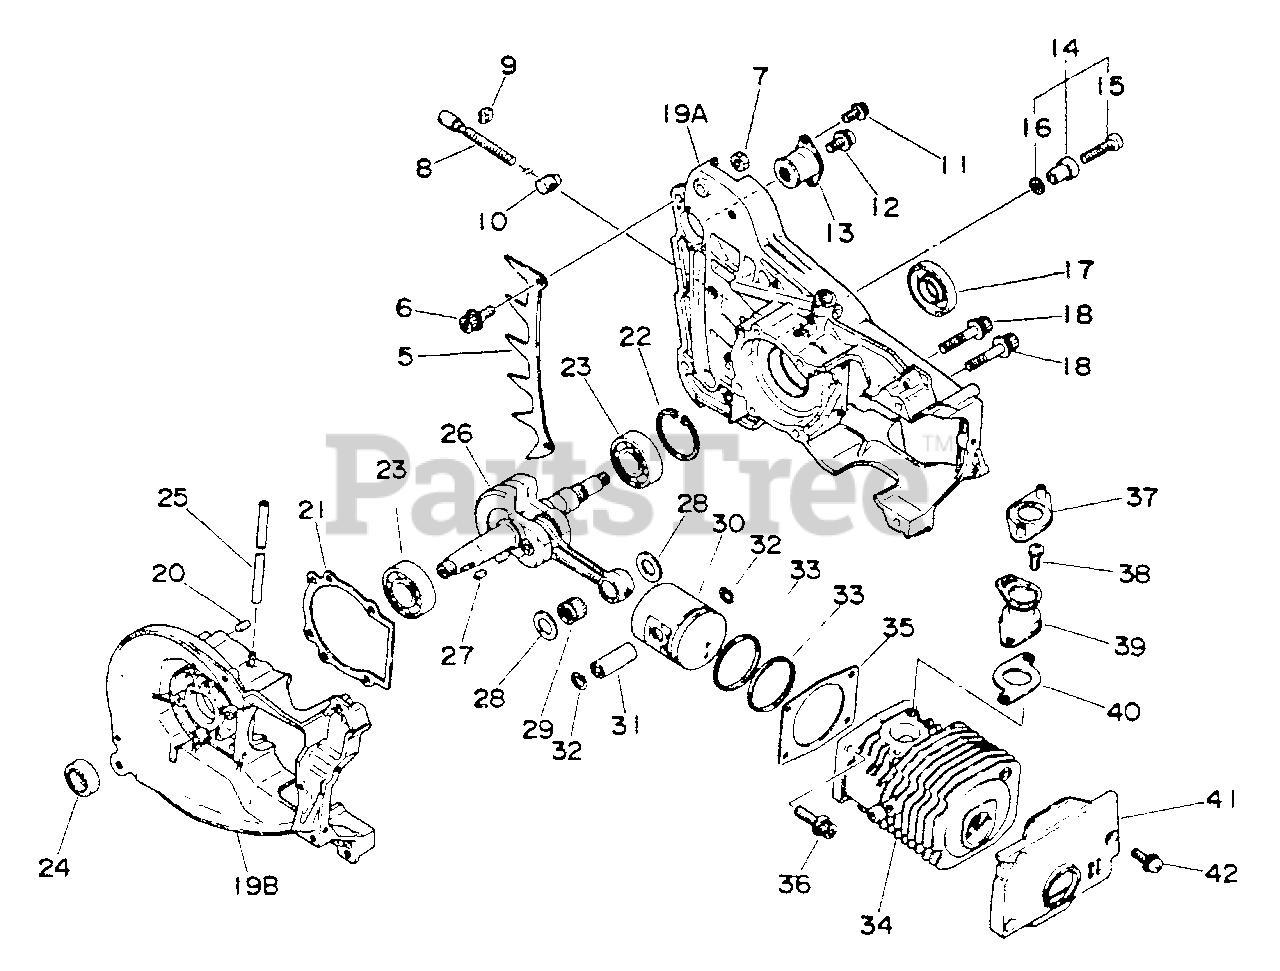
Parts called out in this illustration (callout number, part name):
5	SPIKE, BUMPER
6	BOLT 5×12
7	LOCKNUT - 5
8	SCREW, ADJUSTER
10	TENSIONER, CHAIN
11	SCREW 4×10
12	SCREW 5×10
14	CHAIN CATCHER KIT
15	SCREW 5×25
16	WASHER, FLAT 5.5×10×0.8
17	SEAL, OIL 18
18	BOLT 5×30
19	CRANKCASE KIT
19A	CRANKCASE KIT
19B	CRANKCASE KIT
20	PIN, LOCATING 4
21	GASKET, CRANKCASE
22	RING, SNAP 35
23	BEARING, BALL 6202
24	SEAL, OIL
25	PIPE, IMPULSE 3×6×75
26	CRANKSHAFT ASSY
27	KEY, WOODRUFF
28	WASHER, THRUST
29	BEARING, NEEDLE
30	PISTON
31	PIN, PISTON
32	RING, SNAP 8
33	RING, PISTON
34	CYLINDER
35	GASKET, CYLINDER
36	BOLT 5×20
38	SCREW 5×10
39	ADAPTOR, INTAKE
40	GASKET, INTAKE
41	COVER, CYLINDER
42	SCREW 4×14
